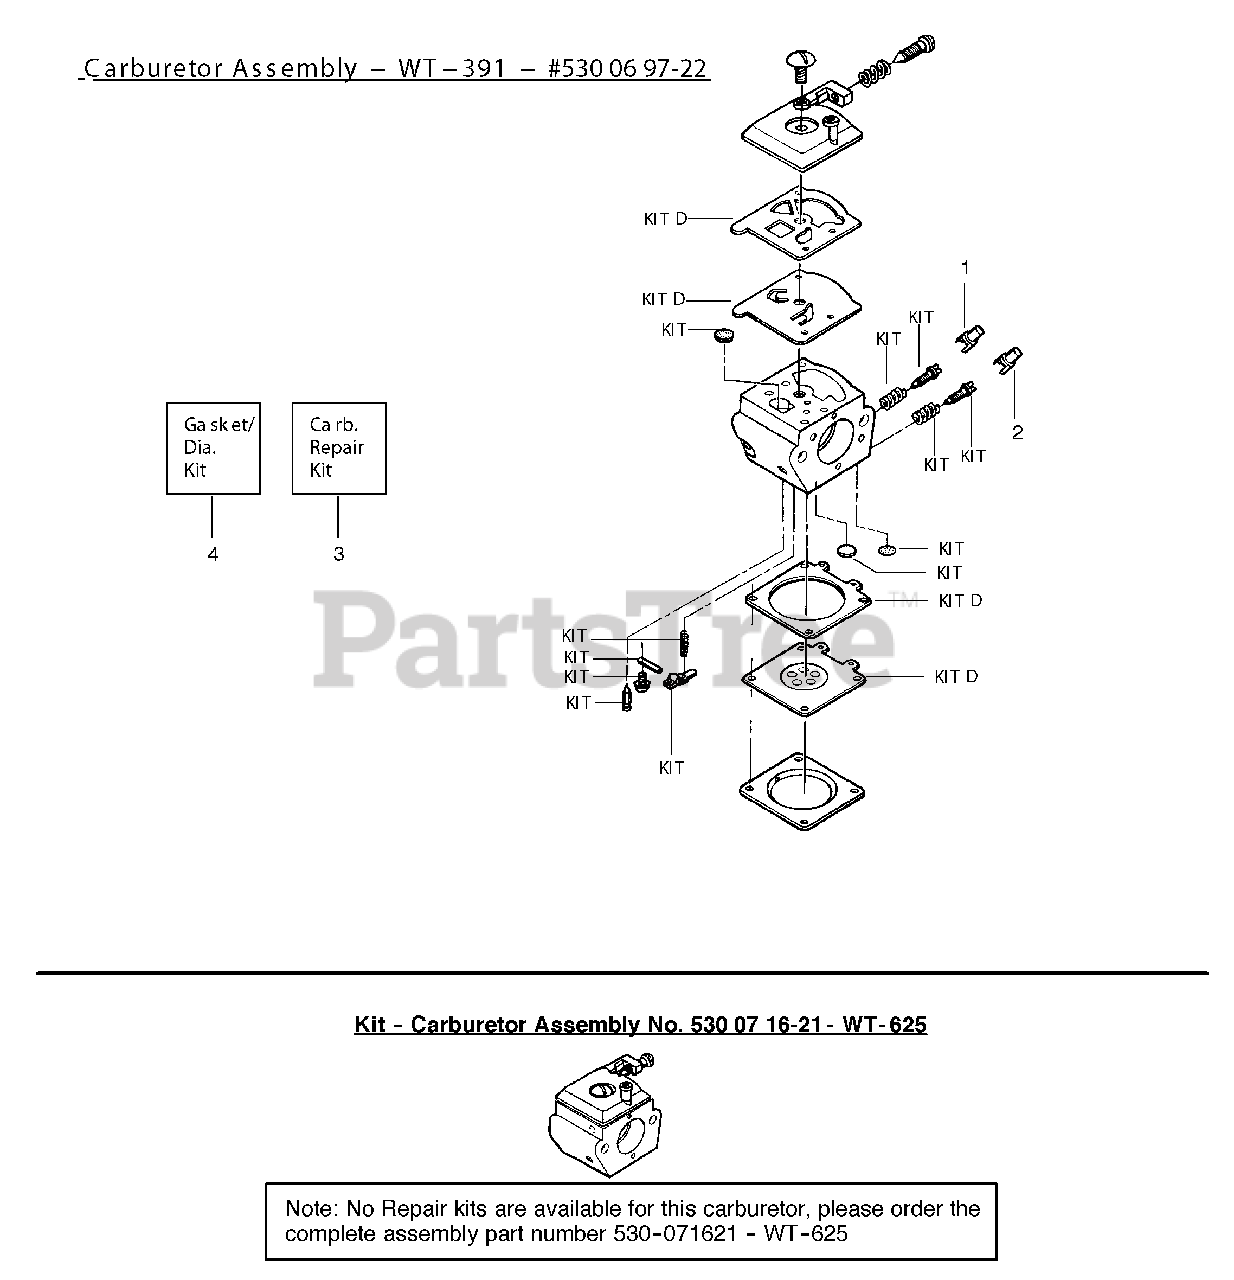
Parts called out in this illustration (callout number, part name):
1	LIMITER CAP-HIGH
2	LIMITER CAP-LOW
3	CARB REPAIR KIT
4	GASKET/DIAPHRAGM KIT
